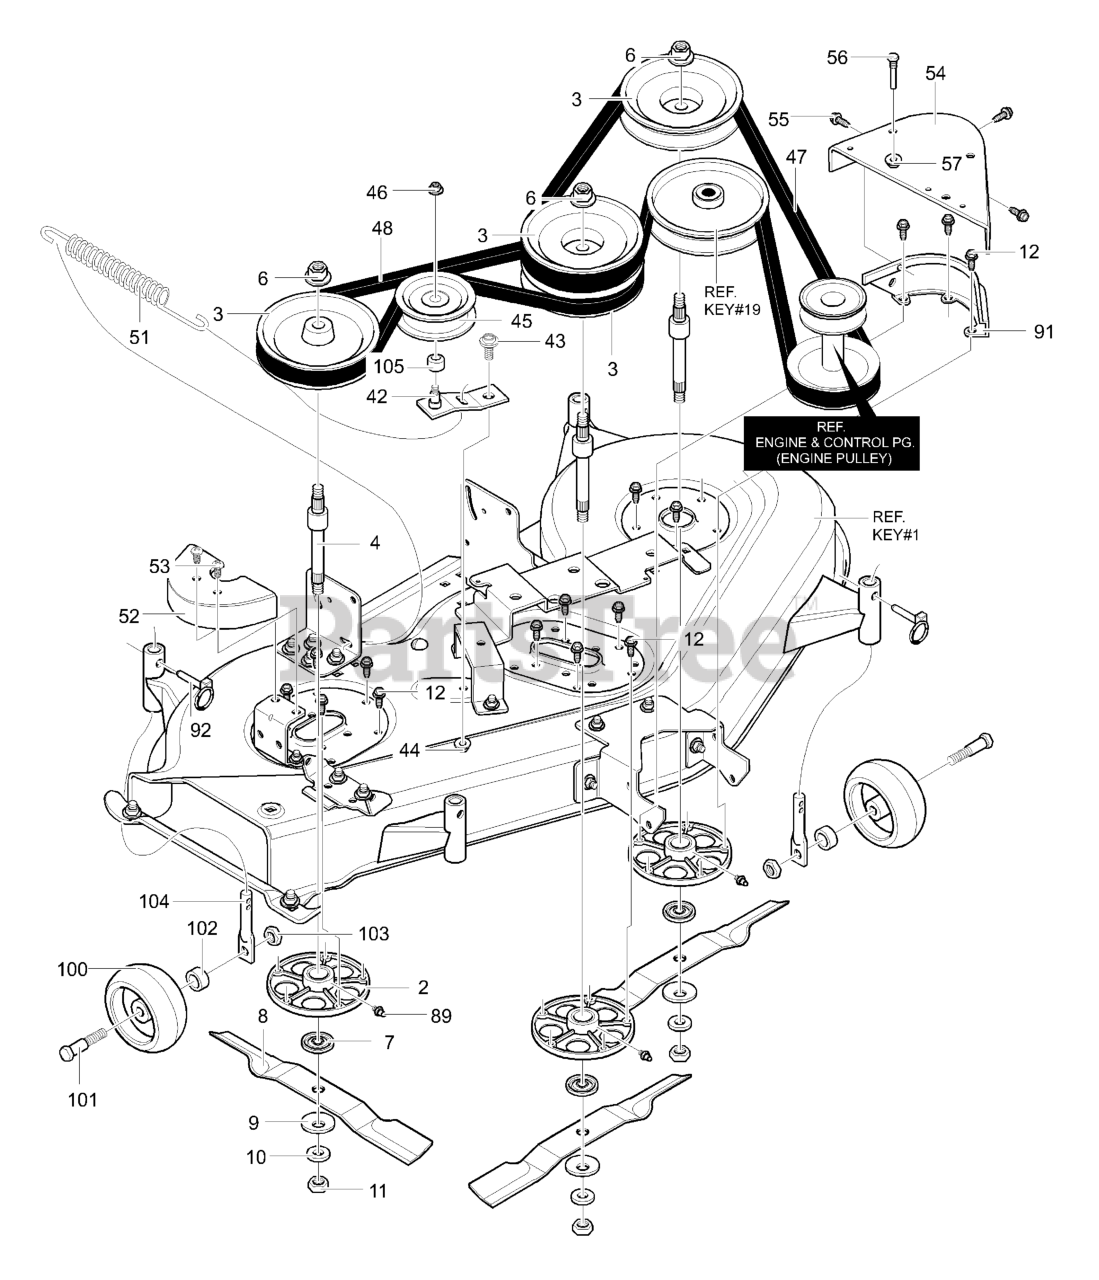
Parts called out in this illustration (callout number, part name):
2	HOUSING, JACKSHAFT
3	PULLEY, SPLIT STEEL
4	SHAFT, SPLINED JACKSHAFT
7	HUB, BLADE ADAPTOR
8	BLADE
12	BOLT
42	IDLER ARM, SECONDARY
45	PULLEY, IDLER
47	BELT, PRIMARY
48	BELT, SECONDARY
51	SPRING, EXTENSION
52	COVER, RIGHT PULLEY
54	COVER, LEFT PULLEY
55	SCREW
56	SCREW, GUIDE
89	ZERK, GREASE
91	BRACKET, PULLEY COVER
92	PIN, LYNCH
100	WHEEL, GAUGE
103	NUT
104	ROD, GAUGE
105	SPACER 1/2 TO 17MM
